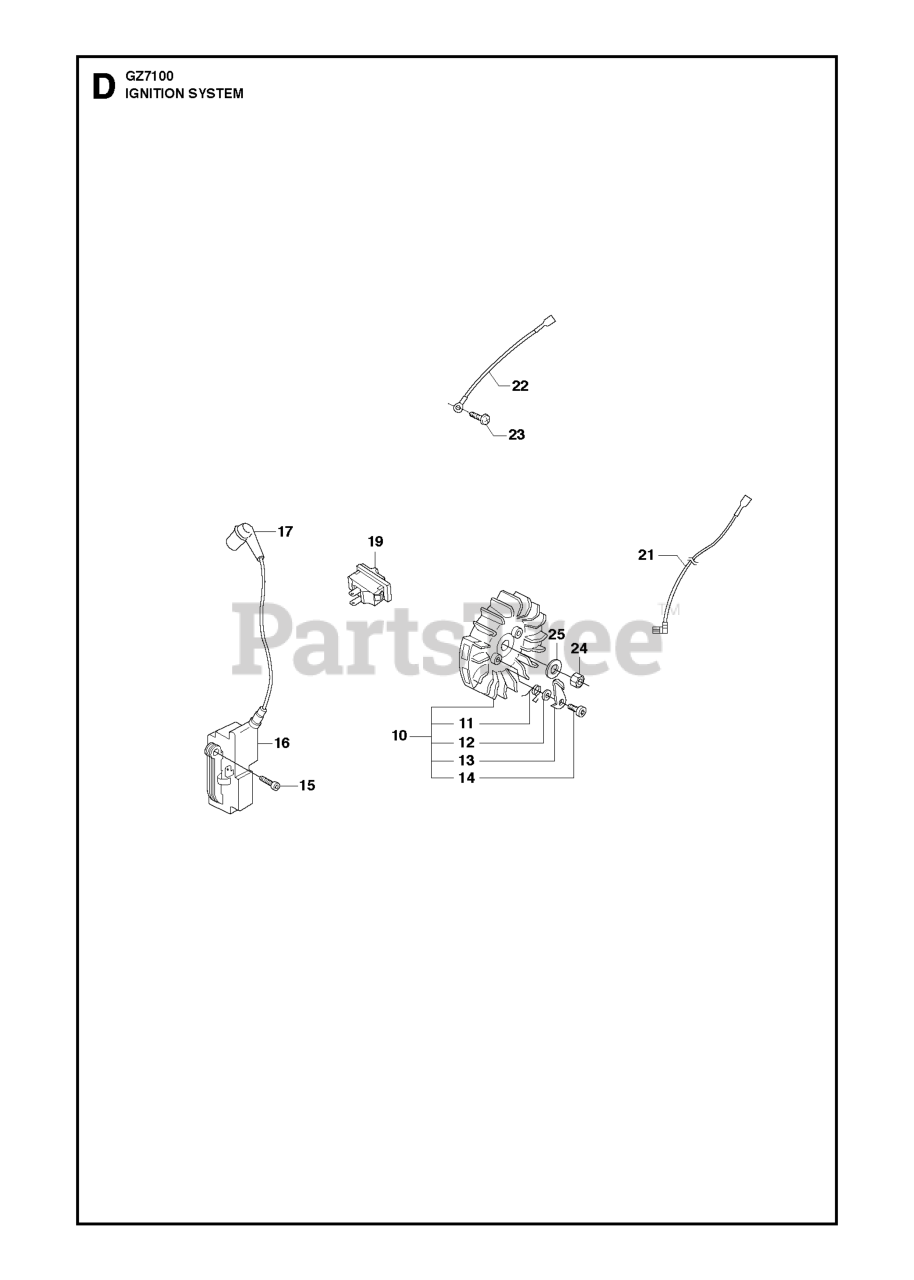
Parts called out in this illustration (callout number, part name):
10	FLYWHEEL
11	SPRING
12	WASHER
13	PAWL
14	SCREW
15	SCREW ITXSCM M5X20 T27 12.9 T
16	IGNITION MODULE
17	SPARK PLUG CONN. KIT
19	START/STOP SWITCH
23	SCREW CITXPANT
24	NUT M8X1
25	WASHER 8.4X16
